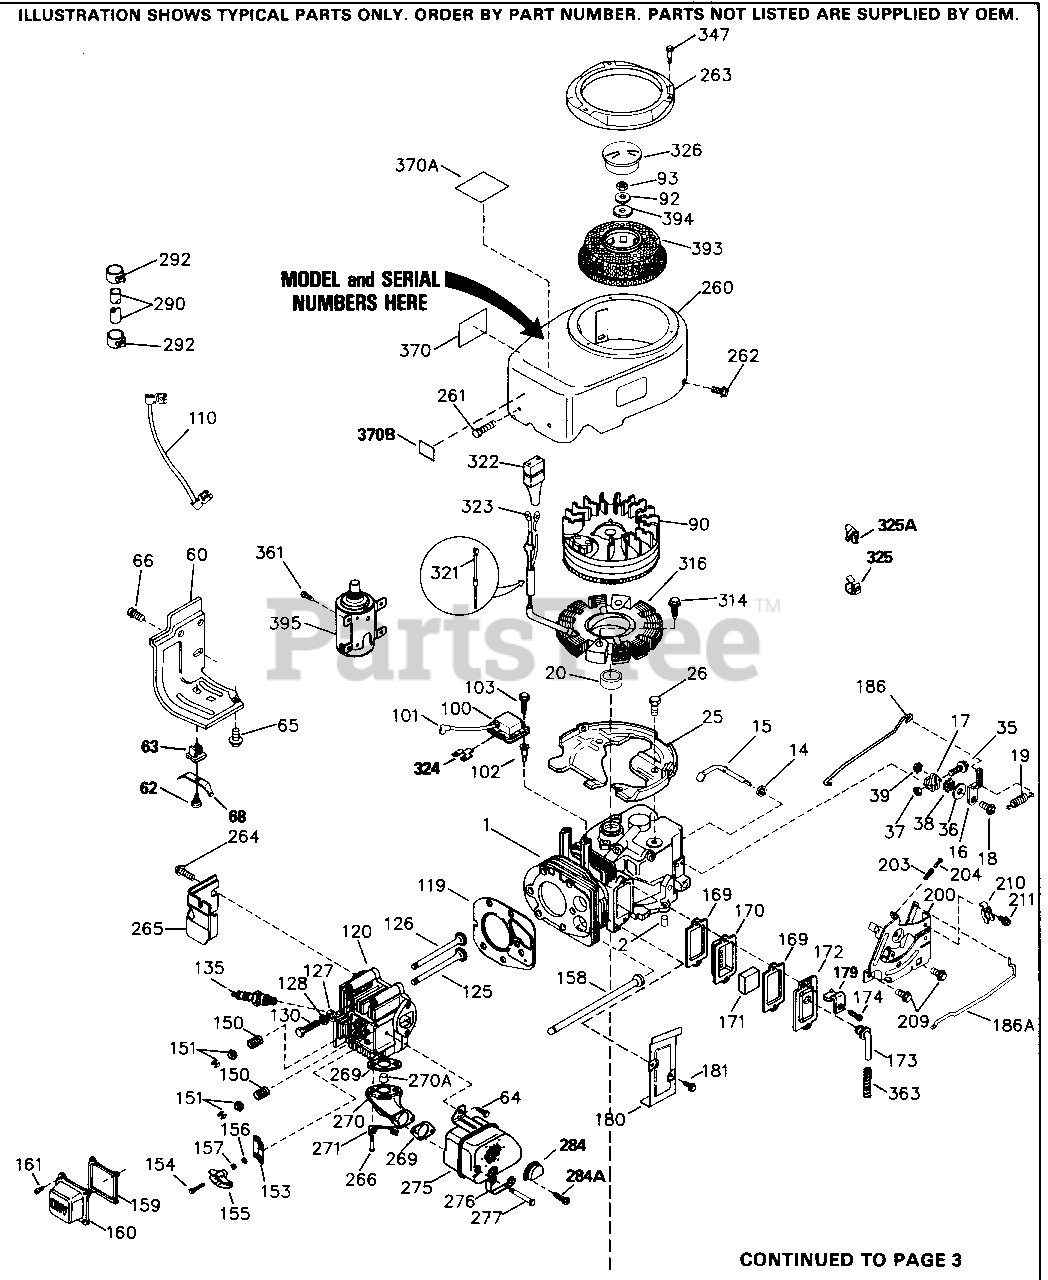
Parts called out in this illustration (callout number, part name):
1	"Cylinder (Incl. 2 & 20)
2	Dowel Pin
14	Flat Washer
15	Governor Rod
16	Governor Lever (Incl. 212A)
17	Governor Lever Clamp
18	Screw, 8-32 x 5/16"
19	Extension Spring
20	Oil Seal
25	Blower Housing Baffle
26	Screw, 1/4-20 x 5/8"
28	Lock Nut, 8-32
35	Screw, 10-32 x 3/4"
36	Lock Washer #8
37	Lock Nut, 10-32
38	Retaining Ring
60	Blower Housing Extension
65	Screw, 10-24 x 1/2"
66	Screw, 5/16-18 x 15/32"
90	Flywheel (W/Ring Gear)
92	Lock Washer
93	Flywheel Nut
100	Solid State Ignition
101	Spark Plug Cover
102	Solid State Mounting Stud
103	Screw, Torx T-15, 10-24 x 15/16"
110	Ground Wire
119	* Cylinder Head Gasket
120	Cylinder Head
125	Exhaust Valve (Std.)
125	Exhaust Valve (1/32" OS)
126	Intake Valve (Std.)
126	Intake Valve (1/32" OS)
128	Belleville Washer
130	Screw, 5/16-18 x 2-45/64"
135	Resistor Spark Plug (RN4C) also avail able in Packaged Part #740069
150	Valve Spring
151	Valve Spring Keeper
153	Push Rod Guide
154	Rocker Arm Stud
155	Rocker Arm
156	Lock Washer
157	Lock Nut, 5/16-24
158	Push Rod
159	* Rocker Arm Cover Gasket
160	Rocker Arm Cover
161	Screw, T-30, 1/4-20 x 1/2"
169	* Breather Gasket
170	Breather Body
171	Breather Element
172	Valve Cover
173	Breather Tube
174	Screw, 10-24 x 1/2"
180	Blower Housing Extension
181	Screw, 10-24 x 9/16"
186	Governor Link
186A	Choke Link
200	Control Bracket (Incl. 203 & 204)
203	Compression Spring
204	Screw, 6-32 x 21/32"
209	Screw, 10-32 x 7/16"
210	Conduit Clip
211	Screw, 10-32 x 3/8"
212A	Bushing
238	Screw, 10-32 x 5-1/4"
245A	Pre-Cleaner Air Filter also available in Packaged Part #740015B
260	Blower Housing
261	Screw, T-30, 1/4-20 x 1/2"
262	Screw, T-40, 5/16-24 x 21/32"
263	Trim Ring
264	Screw, 5/16-18 x 5/8"
265	Cylinder Head Cover
266	Screw, 5/16-18 x 1-1/4"
269	* Exhaust Manifold Gasket
270	Exhaust Manifold
270A	Exhaust Port Liner
271	Locking Plate (Manifold)
290	Fuel Line
292	Fuel Line Clamp
308	Fill Tube Clip
308A	Fill Tube Clip
314	Screw, 1/4-20 x 3/4"
315	Alternator Coil (3/5 Split) Incl. 321 , 322,323
322	Connector Body
323	Terminal
325	Wire Clip
326	Blower Housing Plug
337	Deflector
347	Screw, 10-32 x 9/16"
361	Screw, Torx T-30, 5/16-18 x 15/32"
370	Instruction Decal
370A	Decal - Important Lubrication - SAE 3
395	Electric Starter Motor (12 Volt)
